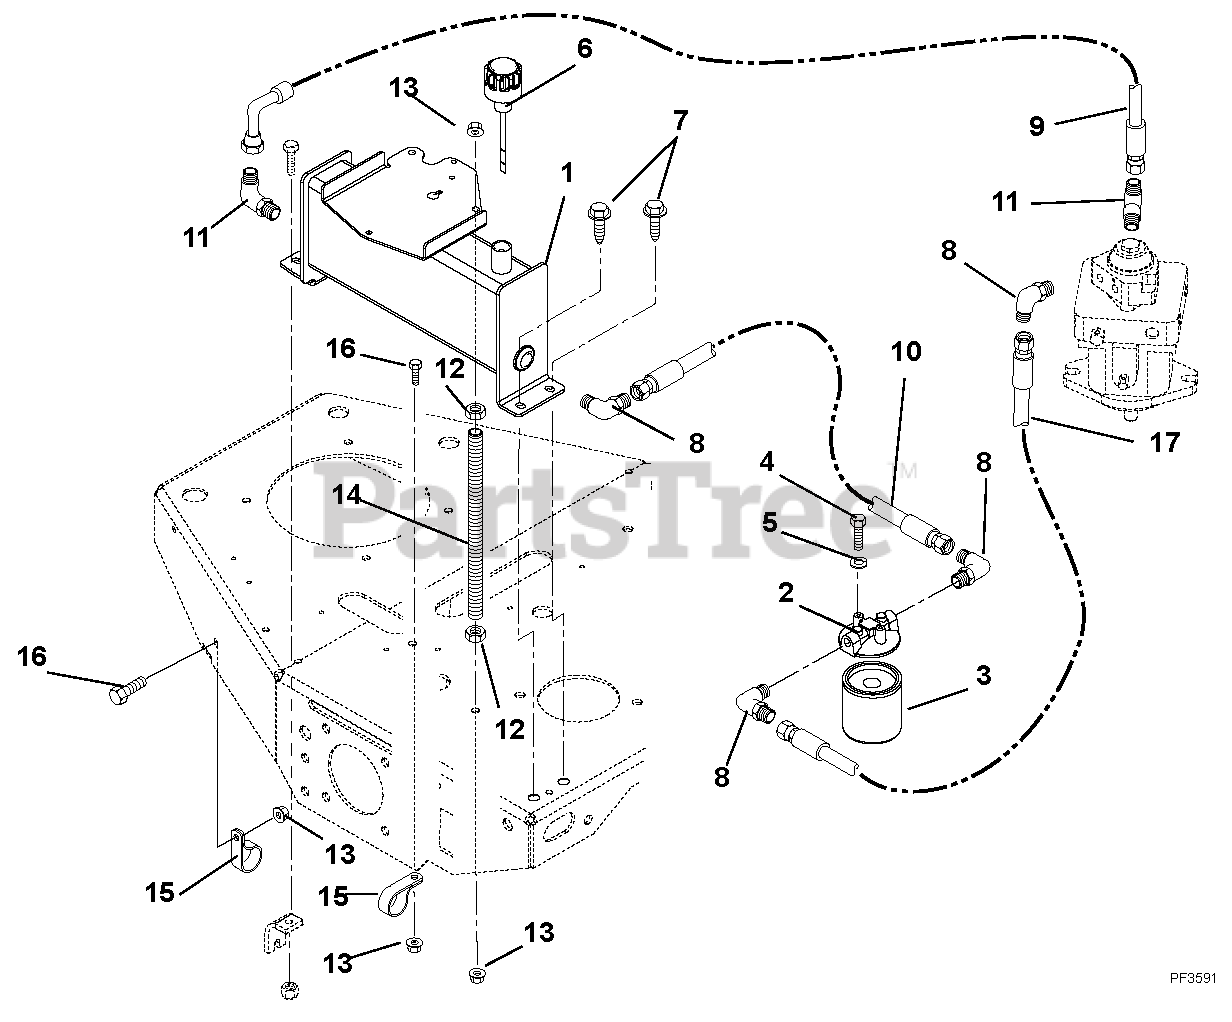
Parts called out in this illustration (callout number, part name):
1	Weldment, Hydraulic Tank
2	Head, Filter
3	Filter, Oil
4	Bolt, Hex .25-20 x .50 Grade 5
5	Washer, Locking .25 x .062 Regular
6	Breather, Dipstick
7	Screw, Tapping .38-16 x .75 Hex Washer Head
8	Fitting, Hydraulic
9	Hose, Hydraulic
10	Hose, Hydraulic
11	Fitting, Hydraulic Elbow
12	Nut, Hex .38-16
13	Nut, Locking Top Flange .38-16
14	Rod, Extension
16	Bolt, Hex .38-16 x 1.00 Grade 5
17	Hose, Hydraulic
